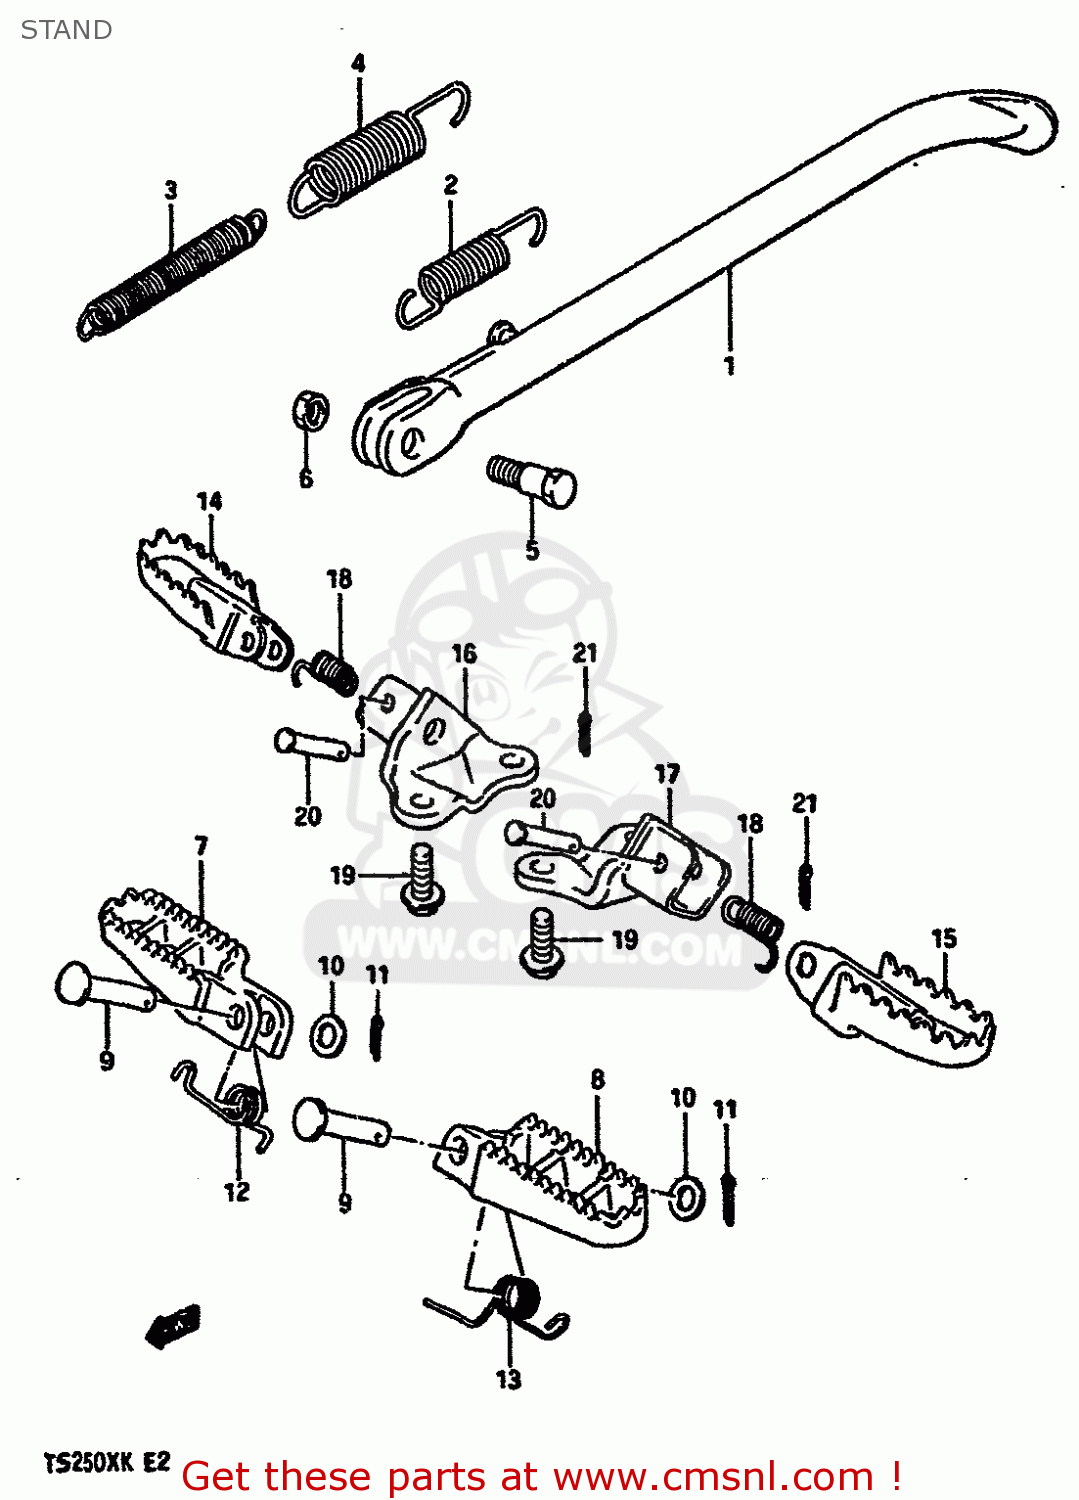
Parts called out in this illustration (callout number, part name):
1	STAND,PROP (BLUE)
2	SPRING
3	SPRING
4	SPRING, OUTER
5	BOLT L:30
6	NUT
7	FOOTREST
8	FOOTREST
9	PIN
10	WASHER
11	PIN 20X20
12	SPRING,FRONT FOOTREST RH
13	SPRING,FRONT FOOTREST LH
14	BAR,PILLION RH (SILVER)
15	BAR,PILLION FOOTREST LH
16	HOLDER,PILLION FOOTREST,R
17	HOLDER,PILLION LH (SILVER)
18	SPRING
19	BOLT
20	PIN
21	PIN 20X20
